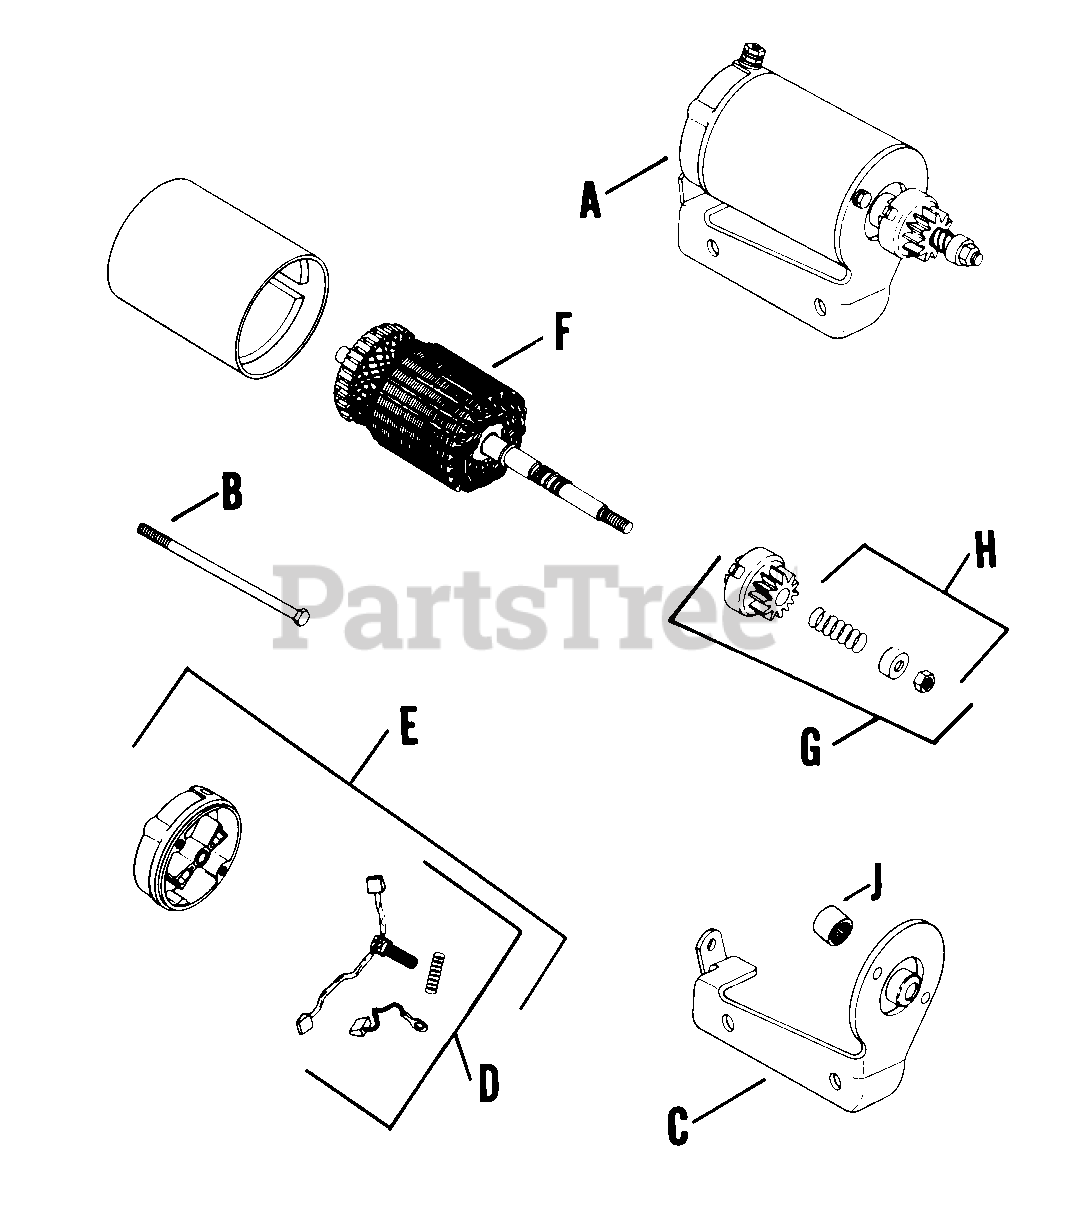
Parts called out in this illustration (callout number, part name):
A	STARTER - USE A-237534
B	BOLT - USE 237758
D	KIT - USE 52 755 15
E	CAP - DISCONTINUED
J	BEARING - DISCONTINUED
